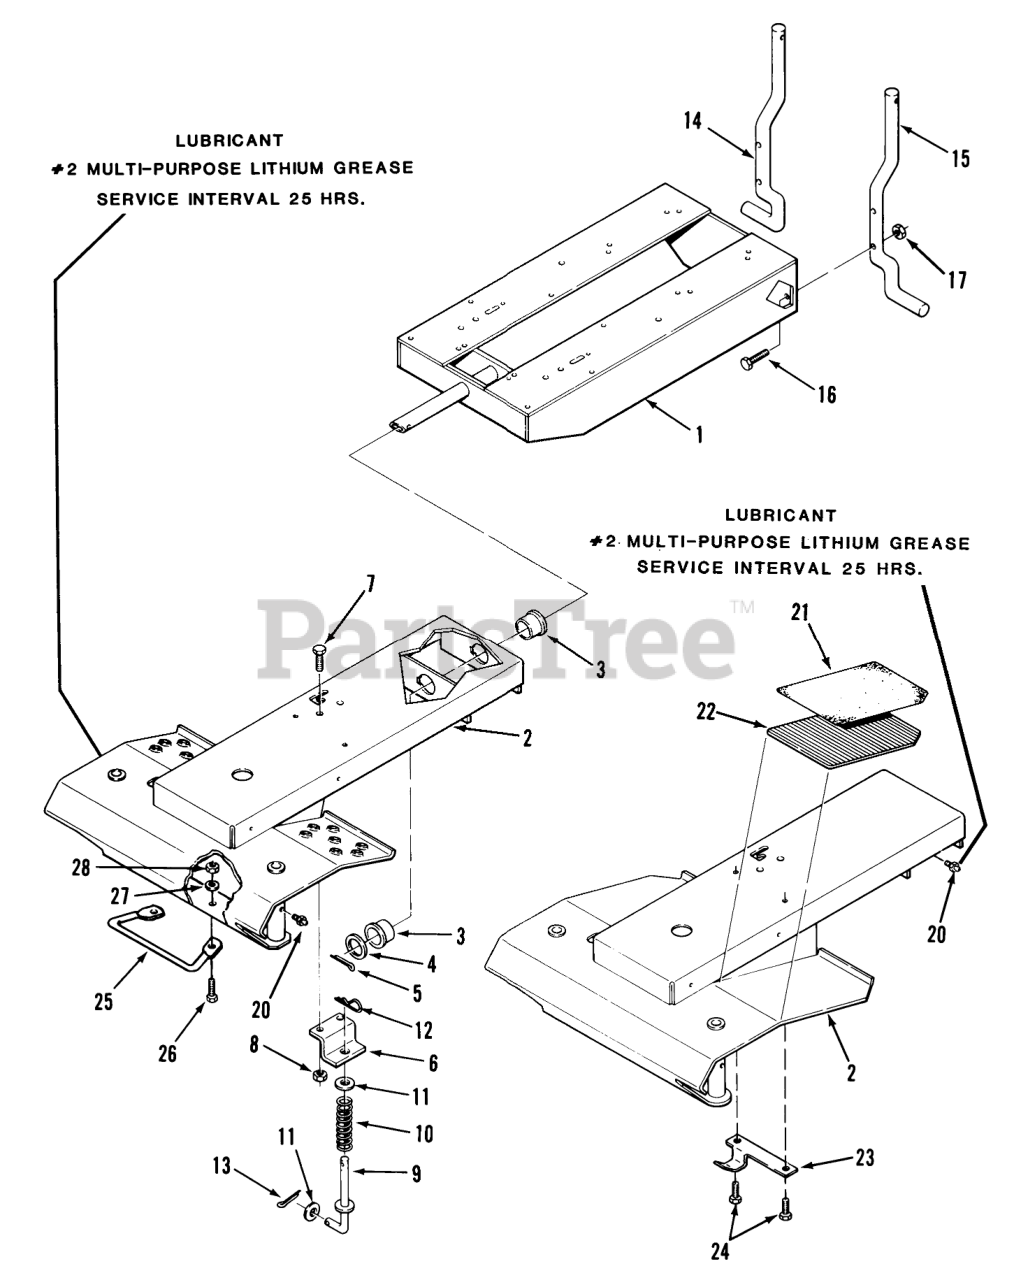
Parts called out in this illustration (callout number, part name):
1	ASS'Y-FRAME REAR R
2	ASSY FRONT FRAME R
3	BEARING FLANGE
4	WASHER
5	Pin-Cotter
6	BRACKET R
7	Bolt
8	NUT
9	ROD ASSY R
10	SPRING-COMPRESSION
11	Washer
12	Hairpin Cotter
13	Cotter Pin
14	REAR ROD RH B
15	REAR ROD LH B
16	BOLT 5/16-18X1 1/2
17	Nut
20	Grease Zerk
21	PAD FOOTREST RH
22	PAD FOOTREST RH
23	BRACKET-SWITCH R
24	Screw
25	Lift Handle
26	BOLT 5/16-18 X 3/4
27	WASHER 5/16 SAE
28	Nut
